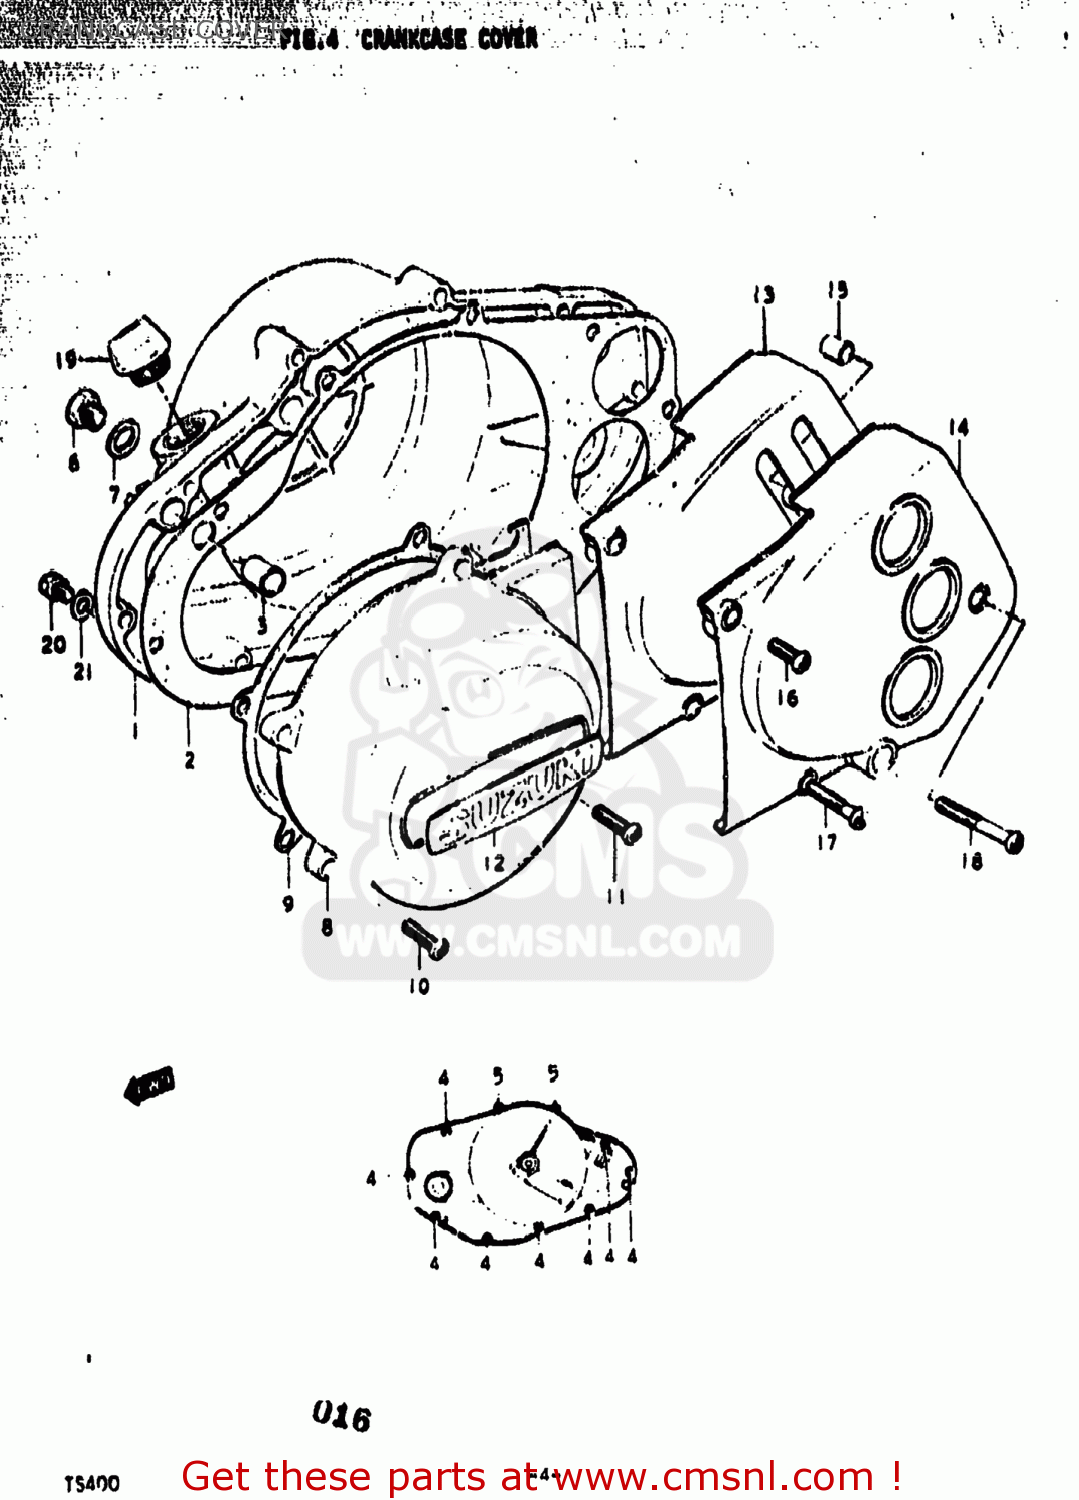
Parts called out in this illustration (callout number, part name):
1	COVER,CLUTCH
2	GASKET,CLUTCH COVER (MCA)
3	PIN
4	SCREW
5	SCREW (6X35)
6	PLUG
7	GASKET(10X14X3.6) (NAS)
8	COVER
9	GASKET,MAGNETO COVER (MCA)
10	SCREW
11	SCREW
12	EMBLEM
13	COVER,SPROCKET
14	COVER,SPROCKET
15	PIN
16	SCREW
17	SCREW (6X35)
18	SCREW
19	PLUG,OIL FILTER
20	SCREW(6X10)
21	GASKET(6.2X11X1) (NAS)
